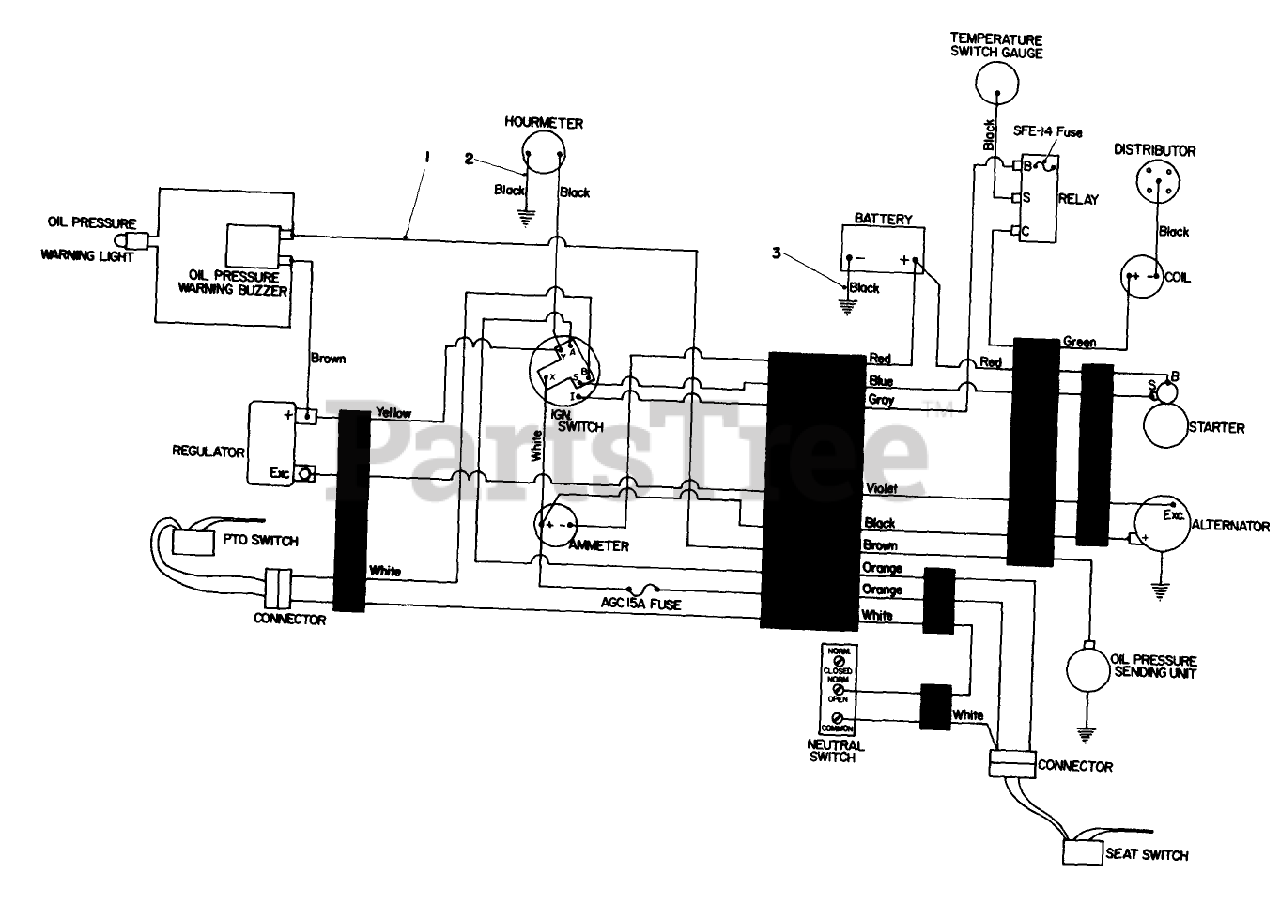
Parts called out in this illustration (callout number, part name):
1	Wire Harness
2	Wire Harness
3	Cable Ground
